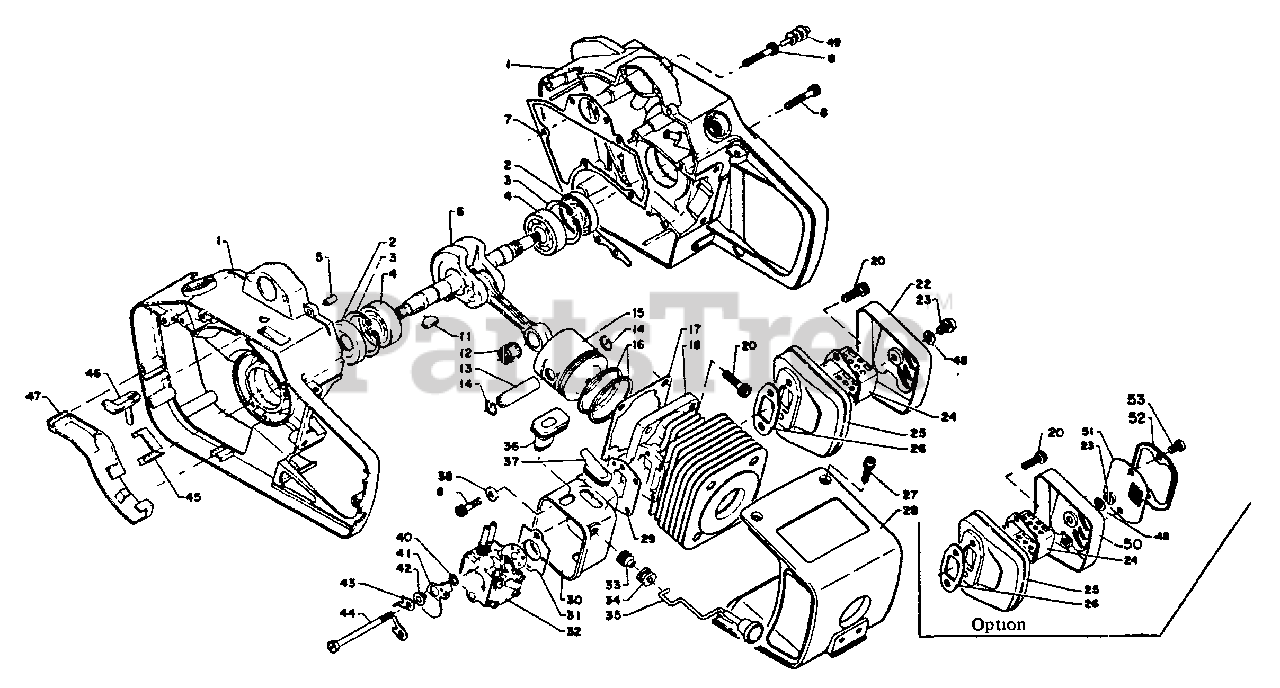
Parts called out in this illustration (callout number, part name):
1	CRANKCASE KIT
2	SEAL, OIL
3	RING, SNAP Ø32
4	BEARING, BALL - 6201 C3
5	PIN, LOCATING 4
6	CRANKSHAFT ASSY
7	GASKET, CRANKCASE
8	BOLT 4×25
12	BEARING, NEEDLE
13	PIN, PISTON
14	RING, RETAINING
15	PISTON
16	RING, PISTON
17	GASKET, CYLINDER
18	CYLINDER
20	BOLT 5×20
22	LID, MUFFLER
23	SCREW 5×8
24	BAFFLE, MUFFLER
25	MUFFLER
26	GASKET, EXHAUST
27	SCREW 4×18
28	COVER, ENGINE
29	GASKET, INTAKE
30	INSULATOR, INTAKE
31	GASKET, INTAKE
32	CARBURETOR - WA-25
33	GROMMET
34	GROMMET, RUBBER
35	ROD, CHOKE
36	GROMMET
37	RUBBER BUSH
38	WASHER
40	WASHER 5.5×8×0.8
41	SHUTTER, CHOKE
43	RETAINER
45	GUIDE, CABLE
46	CLAMP
47	CLAMP
48	WASHER, LOCK 5 MM
49	SEAL, DUST
50	LID, MUFFLER
51	SCREEN, SPARK ARRESTER
52	RETAINER, SCREEN
53	SCREW 5×8
